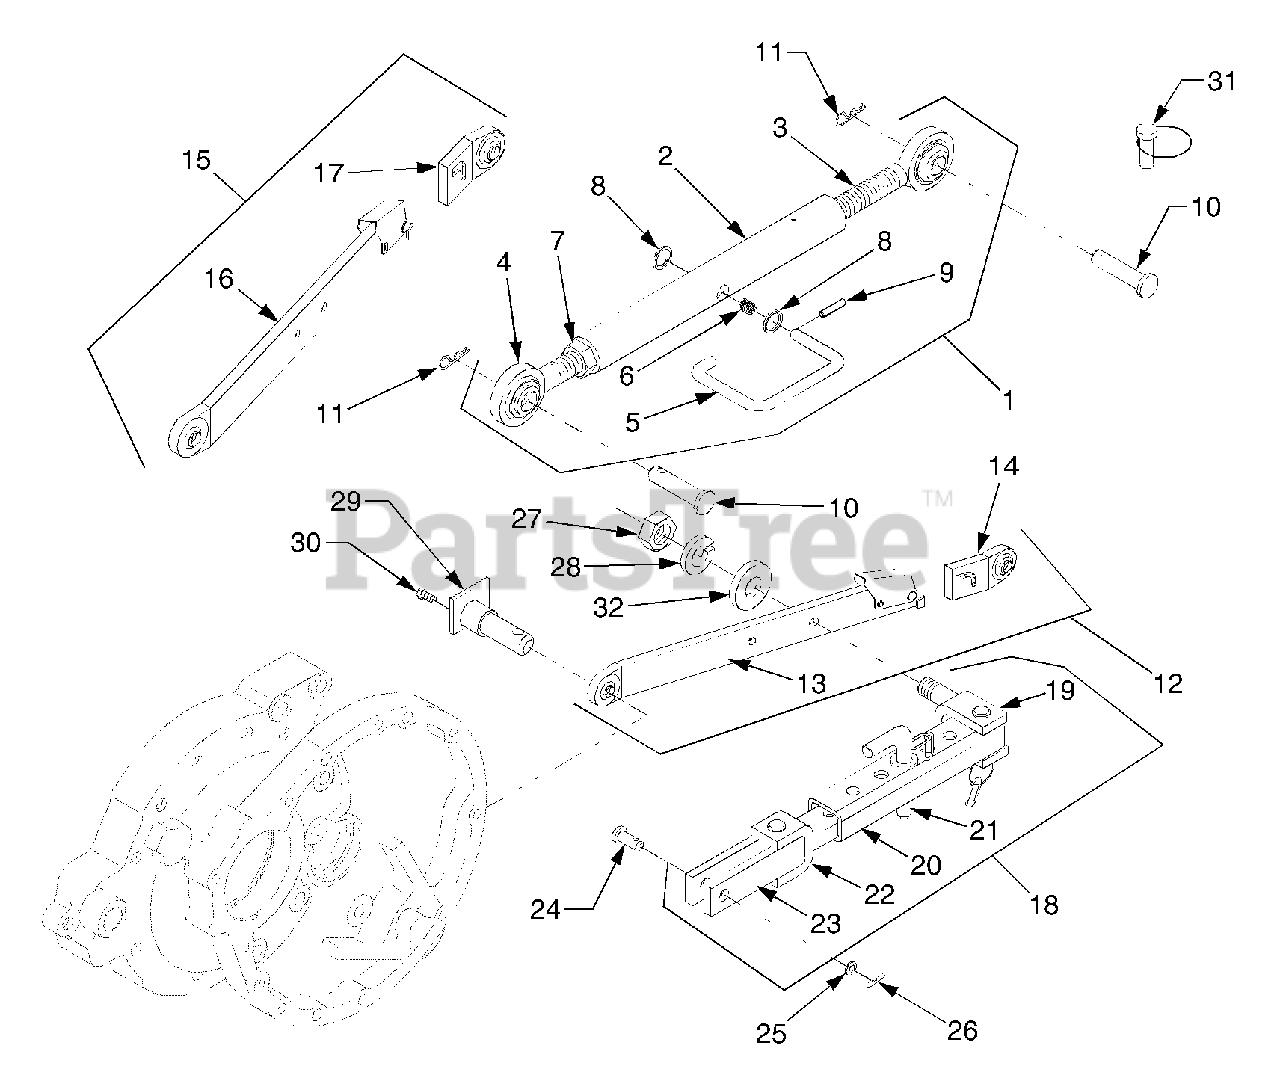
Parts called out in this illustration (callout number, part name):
1	Top Link Ass'y
3	Joint, Ball (LH)
4	Joint, Ball (RH)
5	Support, Top Link
8	Washer, Plain
10	Pin, Top Link
12	Lower Link Ass'y (LH)
13	Body, Lower Link (LH)
14	Houshing, Lower Link (LH)
15	Lower Link Ass'y (RH)
16	Body, Lower Link (RH)
17	Houshing, Lower Link (RH)
18	Check Link Ass'y
20	Housing
21	Hook
22	Bracket 2
25	Washer, Plain
28	Washer, Spring
29	Pin, Lower Link
32	Washer, Plain
